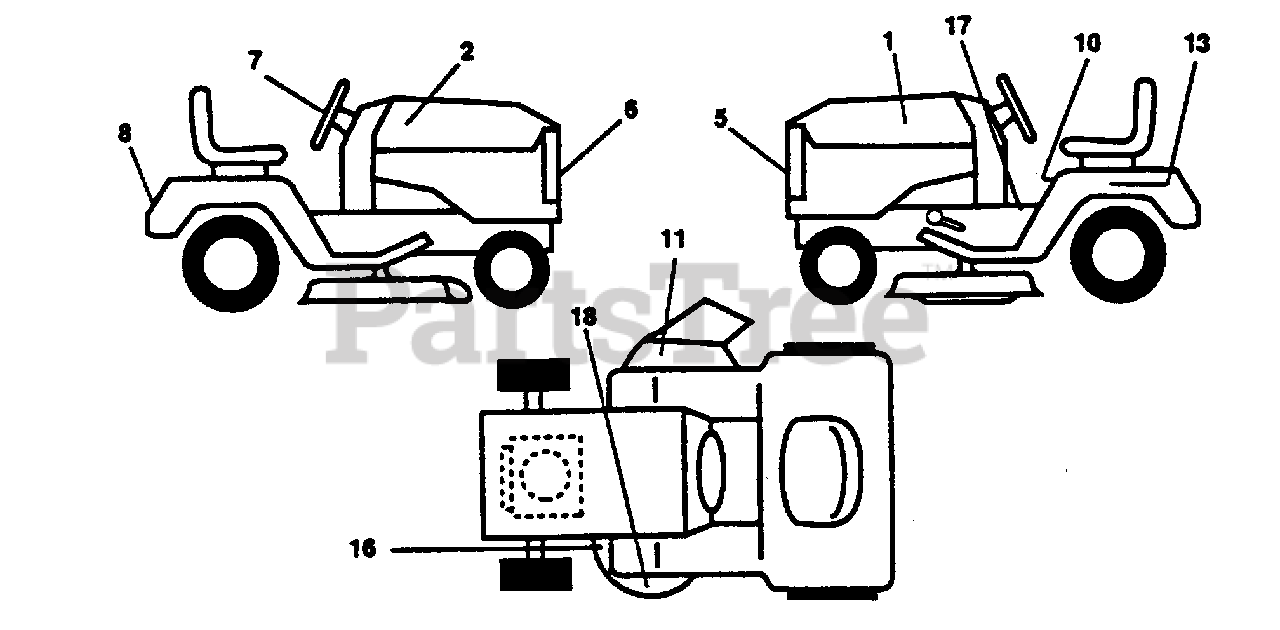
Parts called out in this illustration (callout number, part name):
1	Decal, Hood, L. H.
2	Decal, Hood, R. H.
5	Decal, Grill
6	Decal, Lightbox (AYP part number)
7	Decal, Insert, Stg. Whl.
8	Decal, Fender (AYP part number)
10	Decal, Caution, Fender (AYP part number)
11	Decal, Warning, Cut Finger, (Multi-Lang) (AYP part number)
13	Decal, Caution, Battery (AYP part number)
16	Decal, V-Belt Sch. (AYP part number)
17	Decal, Inst. Oper. (AYP part number)
18	Decal, Deck Enviro (AYP part number)
